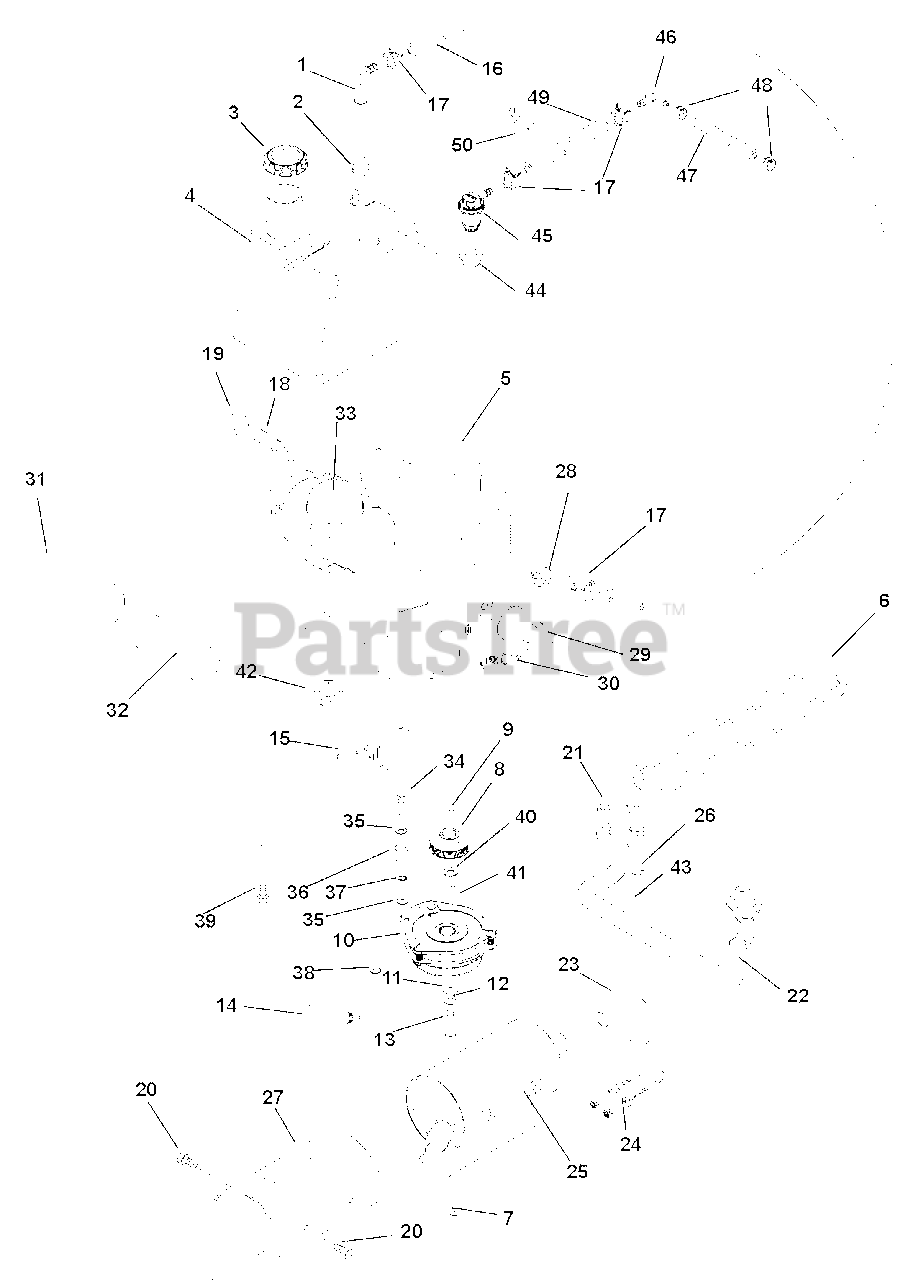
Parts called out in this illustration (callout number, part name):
1	Fitting, Tank
2	Grommet, Dapco Viton
3	Cap, 3.50" Vent-in Ratchet, Fuel
4	Tank, Fuel
5	Engine, 27HP Kawasaki
6	Belt, HA 59.80 Raw Laminated
7	Nut, Locking-Top-Flange .31-18
8	Pulley, 4.46 Dia. x 1.12 Bore
9	Key, Square .25 x 1.00 x .25
10	Clutch, Electric-OGURA GT3.5-VP01R
11	Washer, Flat-Steel .469 x 2.00 x .25
12	Washer, Locking .44 x .109
13	Bolt, Hex .44-20 x 1.50 Grade 5 EP80
14	LocTite™ 271 (Red)
15	Anchor, Clutch
16	Hose, .25 Low-Perm Bulk Gas
17	Clamp, Fuel Line
18	Nipple, Pipe .38 x 6.00 Unfinished Steel
19	Pipe Cap
20	Bolt, Hex M5 –.8 x 8 mm
21	Gasket, Exhaust
22	Manifold, 27HP Kawasaki
23	Tube, Manifold
24	U-Bolt, 1/4-20 x 1.50
25	Muffler (Includes 09066300 Heat Shield)
26	Washer, Locking .31 x .078
27	Heat Shield (Included with 09065600 Muffler)
28	Fuel Filter
29	Filter, Oil - Kawasaki
30	Spark Plug
31	Element, Outer Primary
32	Element, Inner Safety
33	Cap, 2" Air Cleaner Intake
34	Bolt, Hex .38-16 x 1.50 Grade 5
35	Washer, Flat-Steel .406 x .812 x .065
36	Bumper, Rubber .62 x 1.0 x .88 LG
37	Bushing, S.407 x .625 x .813 Steel
38	Nut, Locking Top Flange .38-16
39	Bolt, Hex .38-16 x 1.25 FTH Grade 5 EP30
40	Washer, Thrust 1.125 x 1.750 x .1245
41	Key, Square .25 x 2.50 x .25
42	Clamp, Hose 2.75 Diameter Worm
43	Screw, Socket Head M8 x 1.25 x 20
44	Grommet, Remote Vent Nitrile
45	Valve, Combination
46	Fitting .18 x .25 90° Vacuum
47	Hose .188 Low-Perm Bulk Gas
48	Clamp, Hose Spring .188
49	Hose, Low-Perm Gas .25
